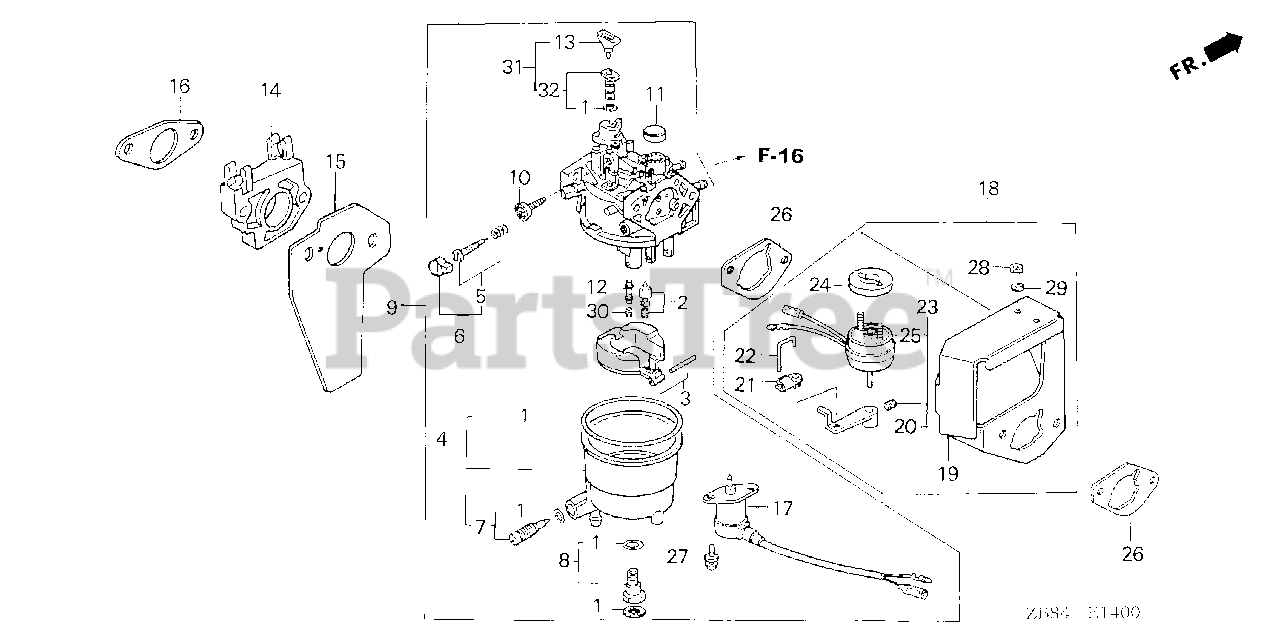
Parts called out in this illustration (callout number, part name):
1	GASKET SET
2	VALVE SET, FLOAT
4	CHAMBER SET, FLOAT
5	SCREW SET, PILOT
7	SCREW SET, DRAIN
9	CARBURETOR ASSY. (BE38A B)
9	CARBURETOR ASSY.
9	CARBURETOR ASSY. (BE38A D)
10	SCREW, THROTTLE STOP
11	CAP, CHOKE DUST
12	NOZZLE, MAIN
14	INSULATOR, CARBURETOR
15	GASKET, CARBURETOR
16	GASKET, INSULATOR
17	VALVE ASSY., SOLENOID
18	STAY ASSY., SOLENOID
19	STAY, CHOKE SOLENOID
20	LEVER, CHOKE SOLENOID
21	JOINT, ROD
22	ROD, CHOKE SOLENOID
23	SOLENOID ASSY., CHOKE
24	SPACER, CHOKE SOLENOID
25	SOLENOID, ROTARY CHOKE
26	GASKET, AIR CLEANER
27	SCREW-WASHER (5X12)
28	NUT, HEX. (3MM)
29	WASHER, SPRING (3MM)
30	JET, MAIN (#92)
30	JET, MAIN (#95)
30	JET, MAIN (#98)
32	JET SET, PILOT (#38)
